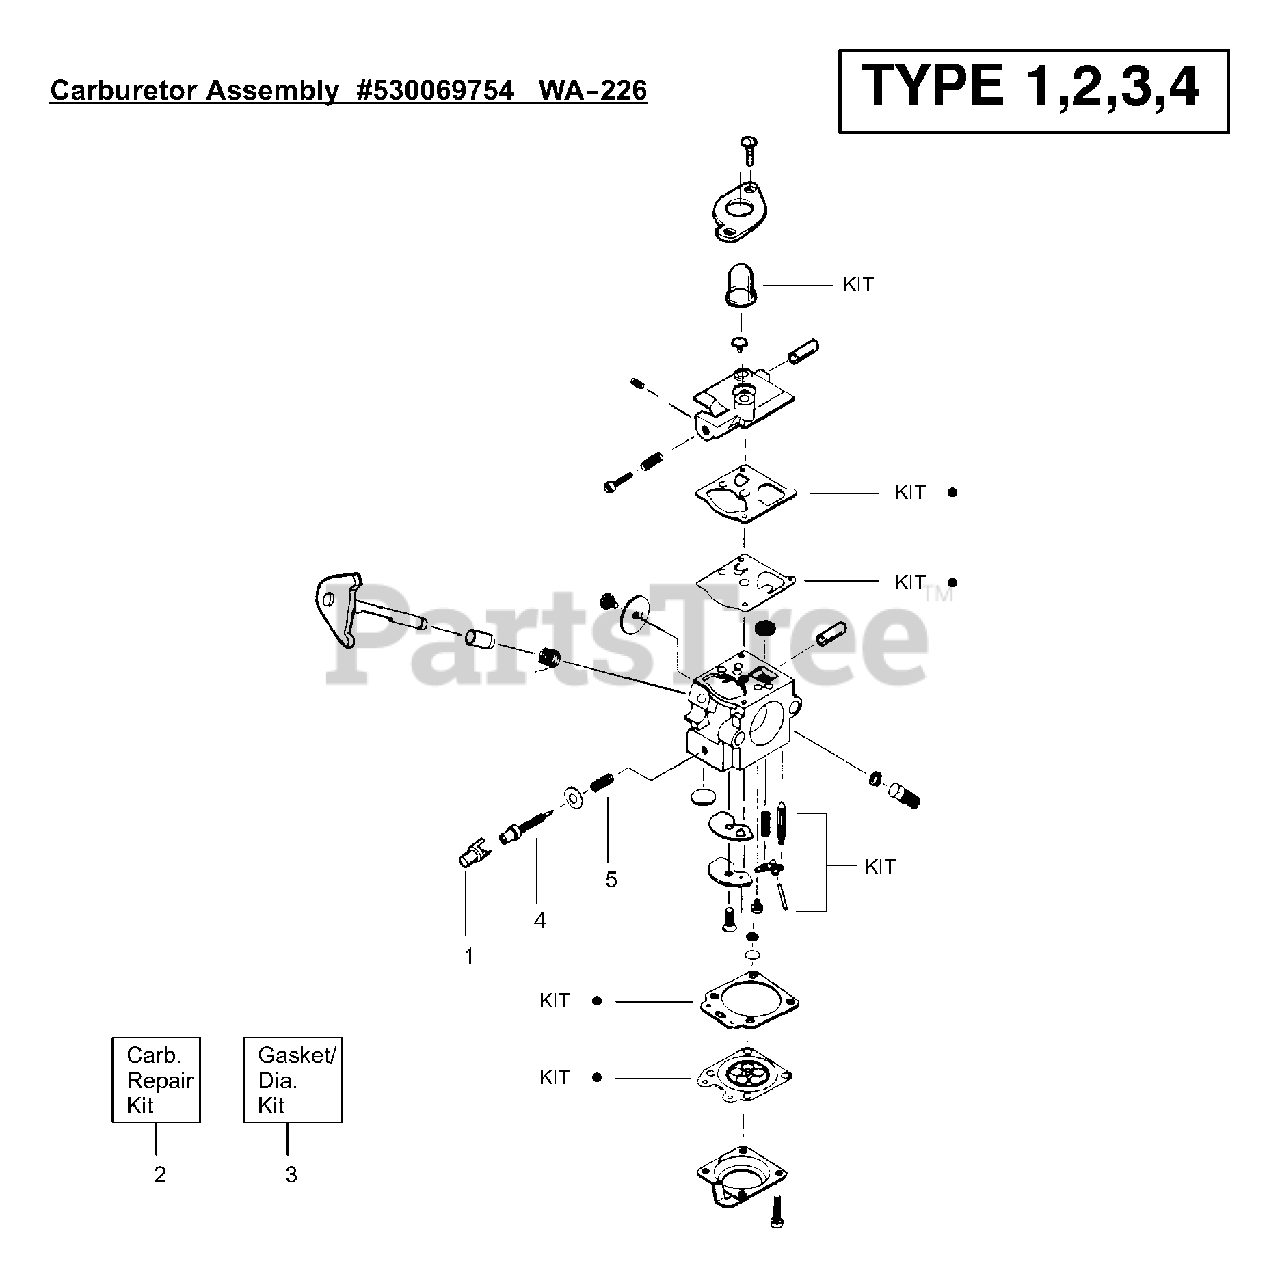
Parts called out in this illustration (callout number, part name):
1	Limiter Cap
2	Carburetor Repair Kit
3	Gasket Diaphragm Kit
4	Needle-Idle
5	Spring-Idle Needle
530069754	Carburetor Assembly (WA226)
